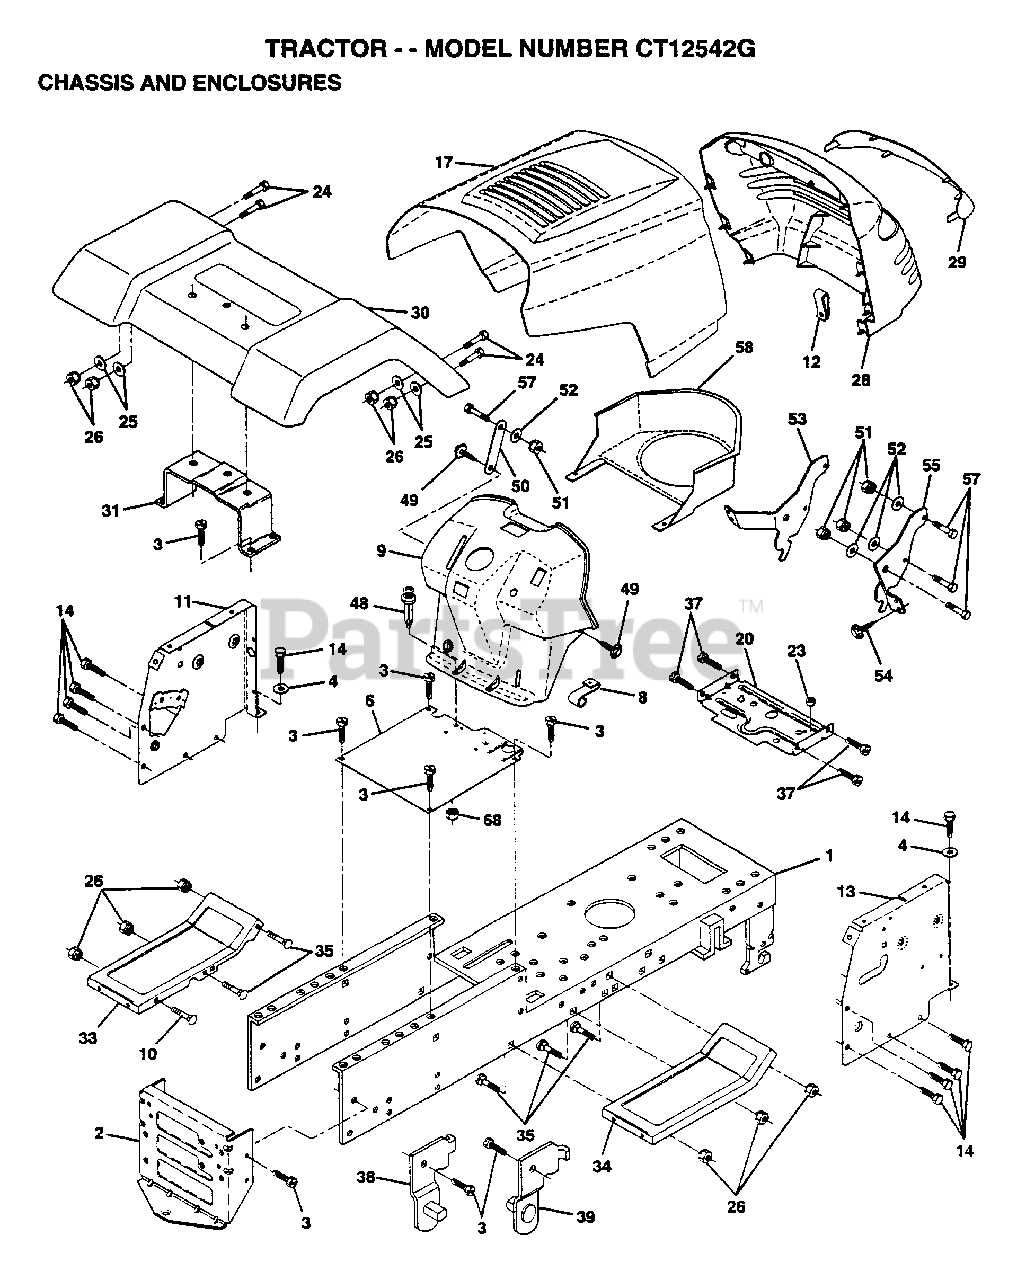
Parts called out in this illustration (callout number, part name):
1	CHASSIS.WLD.11GA
3	SCREW
4	WASHER
8	"CLIP,INSULATOR"
12	CLIP.TINNERMAN
14	SCREW LT
20	PLATE.MTG.BTRY.TK
24	BOLT
25	WASHER
26	NUT
29	LENS GRILLE
31	BRKT FENDER
33	FOOTREST.LH.PERF.
34	FOOTREST.RH.PERF.
35	BOLT
37	SCREW
38	BRACKET ASM LH
39	RIVET.PUSH.PLATE
49	SCREW HEX CRT
50	BRACE SUPT DASH
51	NUT
52	WASHER
53	BRACKET.GRILLE.LH
55	BRACKET.GRILLE.RH
58	DUCT AIR 12-15H
68	NUT
